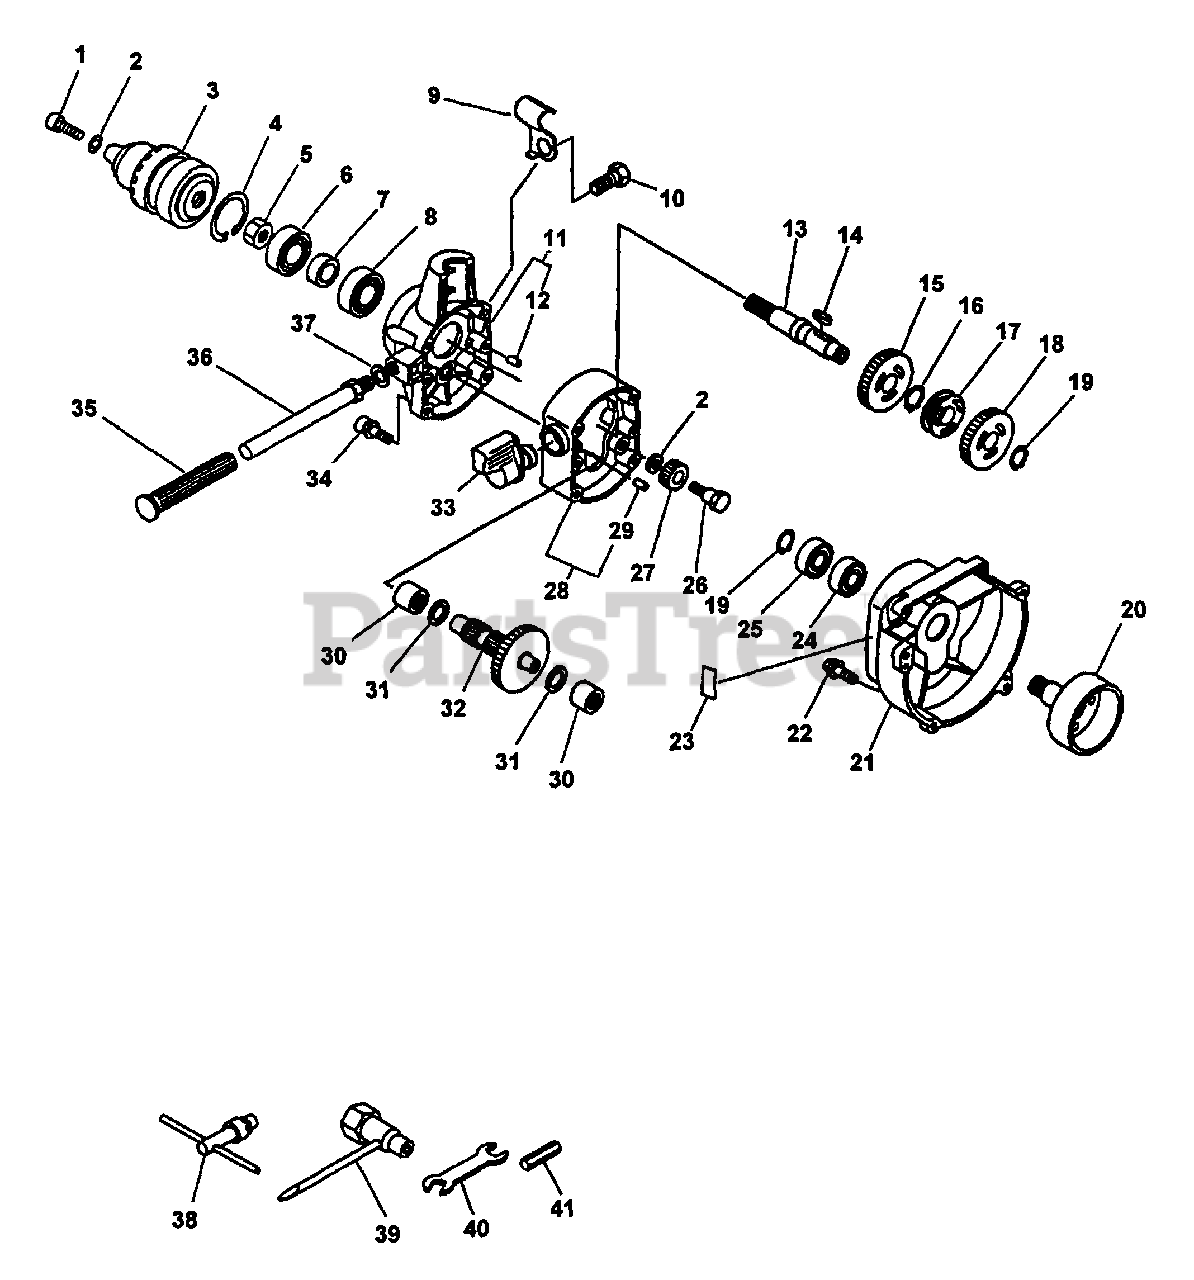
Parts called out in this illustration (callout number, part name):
1	BOLT 6×20
2	WASHER 6
3	CHUCK, KEYED
4	RING, SNAP Ø32
6	BEARING, BALL 6002 DDU
8	BEARING, BALL 6002
9	HOLDER, CHUCK KEY
10	BOLT 10×1.5×15
11	HOUSING, GEAR CASE
12	PIN, LOCATING 4
13	SHAFT, AXLE
14	KEY, WOODRUFF 4×16
15	GEAR, SPUR
16	RING, RETAINING 15
17	NAIL, CLUTCH
18	GEAR, SPUR
19	RING, RETAINING - 12
20	DRUM, CLUTCH
21	COVER, FAN
22	SCREW 4×16
23	LABEL, CAUTION
24	BEARING, BALL 6001
25	BEARING, BALL 6001
26	BOLT, CLUTCH
27	GEAR, SPUR
28	CASE, GEAR
29	PIN, LOCATING 4
30	BEARING, NEEDLE
32	GEAR, SHAFT
33	LEVER, CLUTCH
34	BOLT 5×50
35	GRIP
36	HANDLE, LEFT
37	WASHER 10.5×18×1.6
38	KEY, CHUCK
39	T-WRENCH 10×19 MM
40	SPANNER 17×19
41	BAR, HEX
